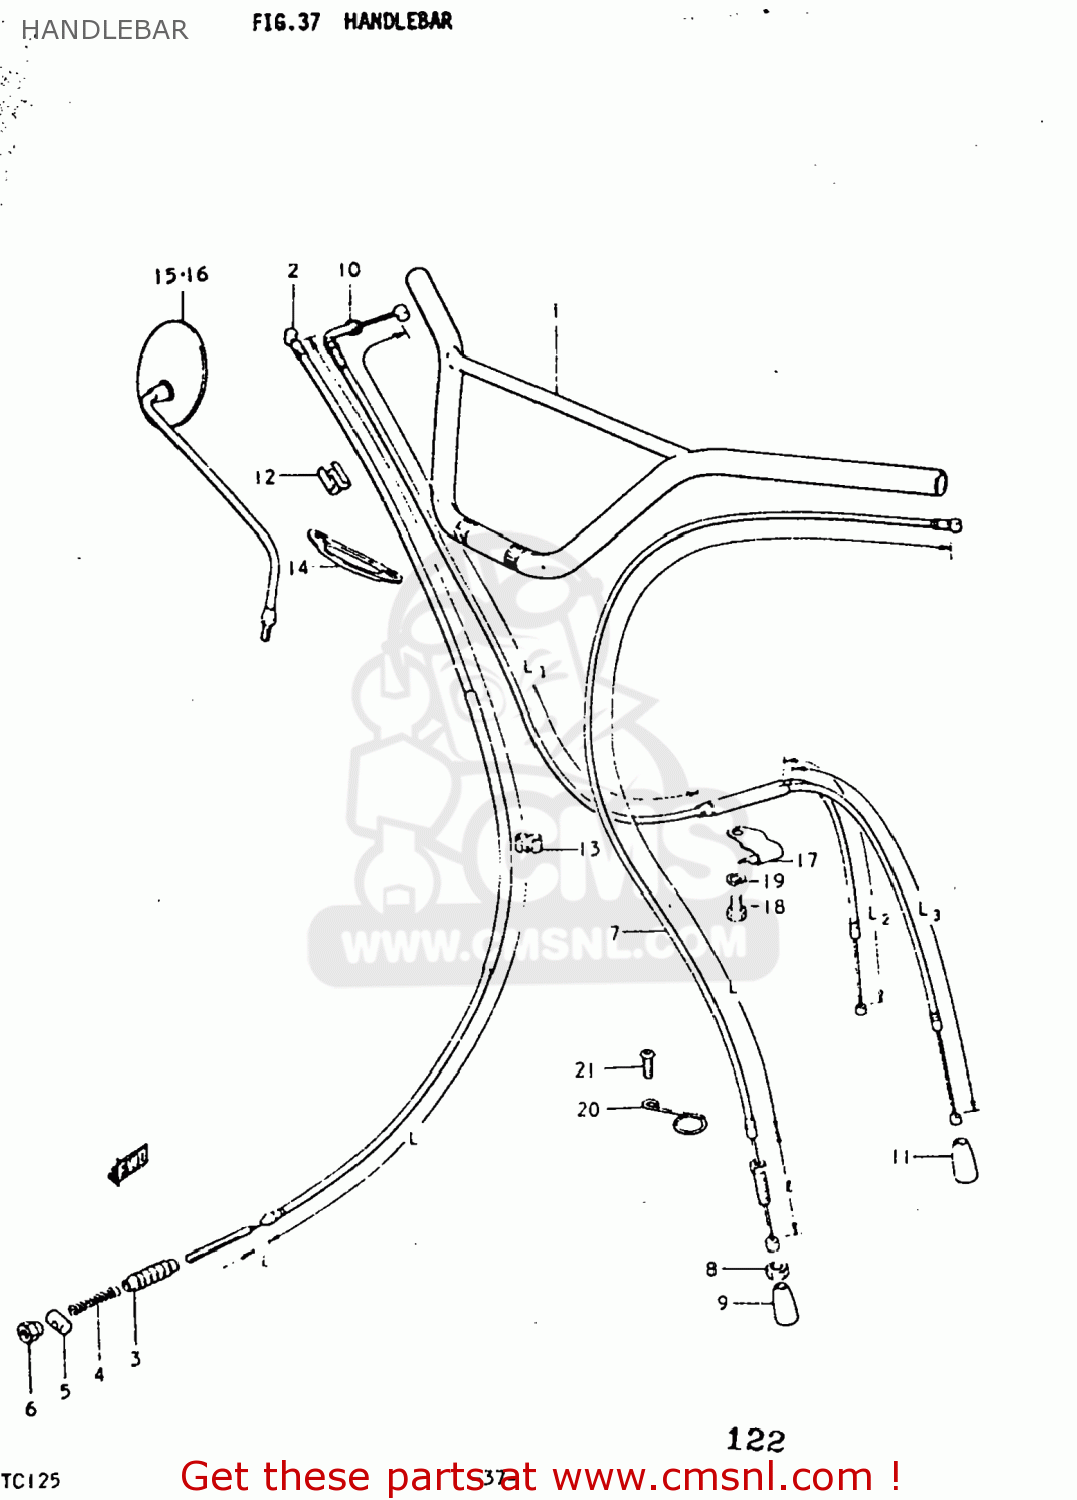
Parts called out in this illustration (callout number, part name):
1	HANDLEBAR
2	CABLE ASSEMBLY,FRONT BRAKE
3	SEAL,DUST(7X16X75)
4	SPRING
5	PIN,10X19
6	NUT
7	CABLE ASSY,CLUTCH
8	NUT
9	SEAL,DUST(7X18X30)
10	CABLE ASSEMBLY,THROTTLE
11	SEAL,DUST(7X18X30)
12	CLIP
13	CLIP
14	GUIDE,CABLE
15	MIRROR ASSEMBLY,RIGHT
16	MIRROR ASSEMBLY,LEFT
17	CLAMP
18	BOLT
19	LOCK WASHER
20	CLIP
21	SCREW 6X12
